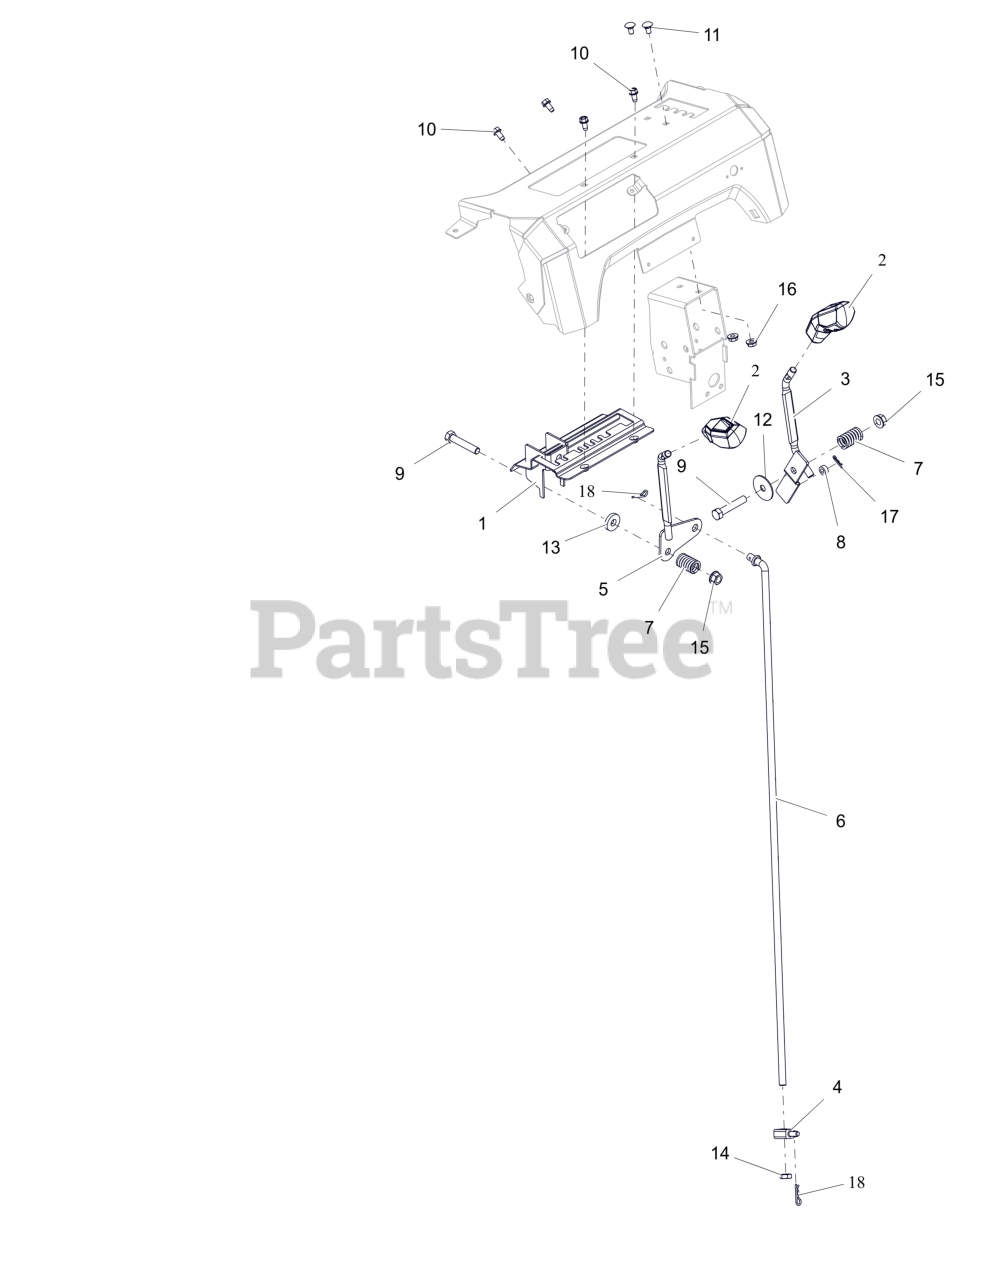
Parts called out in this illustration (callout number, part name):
1	WELDMENT, DETENT PLATE-COMPACT
2	KNOB, CONTROL
3	WELDMENT,SM DASH DEFL CONTROL
4	PIVOT,SHIFT ROD .375-16(TRUNN)
5	LEVER, CONTROL-SHIFT(WELDMENT)
6	ROD, SHIFT - SMALL DASH DELUXE
7	SG-COMP .125X.781X1.250
8	BSHG-SLV .265X.500X.219
9	BLT,HEX .38-16X2.00 G5 ZCC
10	SCR-TAP .25-20X.50 HWH ZCC
11	BLT, RHSN .25-20X.500 G5 ZCC
12	WSHR,FLT .380X1.50X.062 ZCC
13	WSHR, FLT .406X1.00X.188 ZCC
14	NUT-JAM .375-16 G2 ZCC
15	NUT-LK-TOP-FLG .38-16 ZC120
16	NUT-LK-CTR-FLG .25-20 ZC120
17	PIN, HAIR #178 .06X.77 ZCC
18	PIN, HAIR #213 .08X1.19 ZCC
